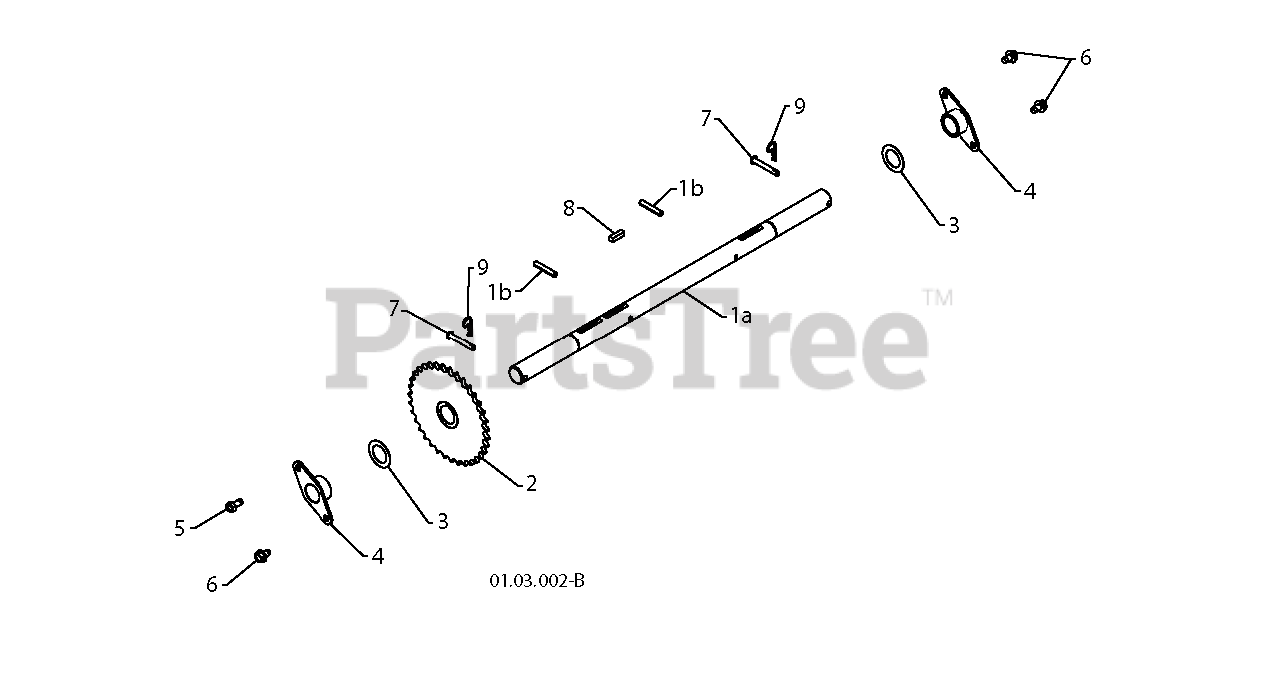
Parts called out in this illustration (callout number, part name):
1	AXLE.ASM.SHAFT.W/ROLLPIN.PS
2	SPROCKET.WELDMENT.AXLE.1.00
3	WASHER 1.00
4	BEARING, AXLE
7	RIVET
8	KEY, SQUARE 1/4 X .875
9	RETAINER M
